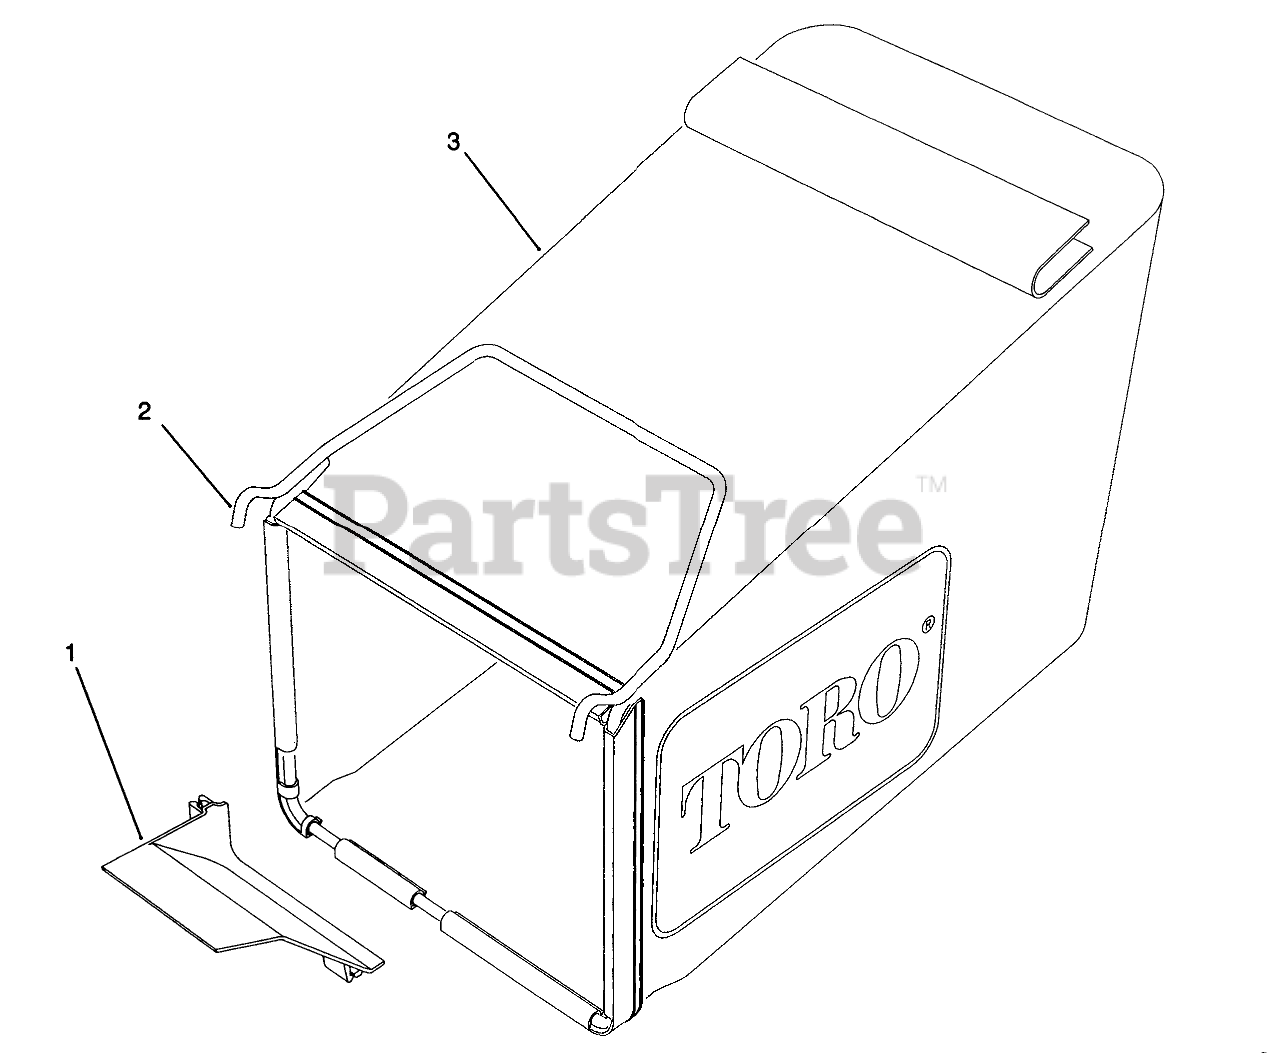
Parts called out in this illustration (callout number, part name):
1	BAG RAMP
2	FRAME WA
3	GRASS BAG REAR EMPTY
